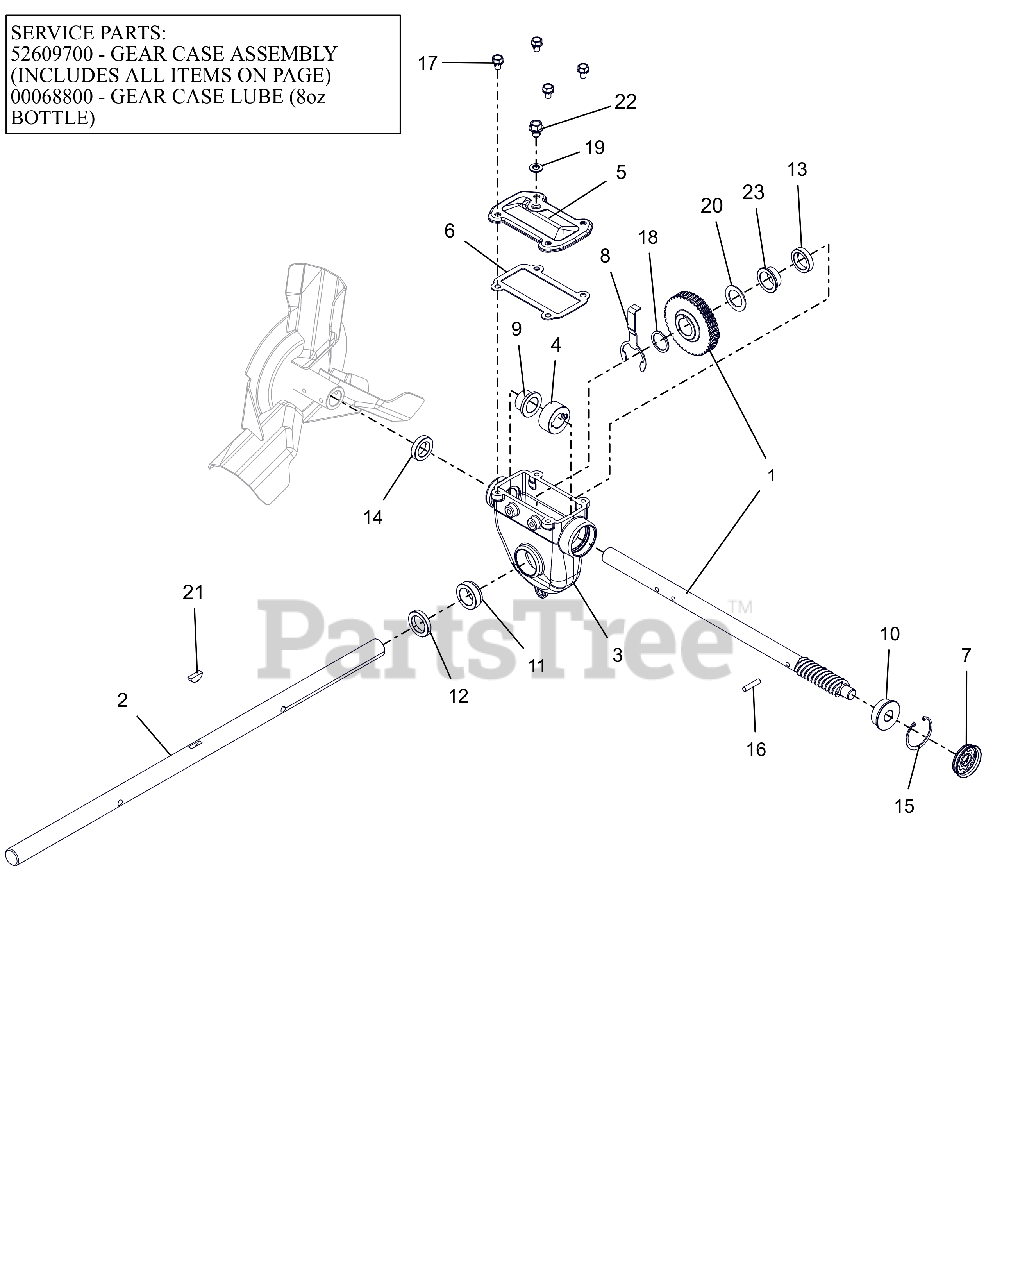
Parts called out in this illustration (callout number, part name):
1	ASSY, WORM SHAFT & GEAR
2	SHAFT, RAKE-28"
3	GEARCASE, LARGE MACHINED
3	GEAR CASE, 28" IRON PRO TOP-LD
3	ARIENS L3 LUBE, 8 OZ BOTTLE
4	THRUST COLLAR, .875"ID SLIPFIT
5	COVER, TOP - LARGE IRON
6	GASKET, TOP - LARGE GEARCASE
7	COVER, GEAR CASE 1.75"
8	BUSHING RETAINER, LARGE
9	BSHG-FLG .879X1.128X.75X1.45
10	BSHG-FLG .628X1.503X.58X1.725
11	BSHG-FLG LARGE, RIGHT
12	SEAL-OIL .999X1.500X.250 TBC29
13	SEAL-OIL .999X1.375X.312 TBC29
14	SEAL-OIL .873X1.375X.312 TBC29
15	RG-RTNG-INT 1.750X.062
16	PIN-STR .250X1.12 6150
17	BLT, SEMS .31-18X.50 G5 ZCC
18	WSHR, FLT 1.010X1.250X.068 ZCC
19	WSHR-BND-SEAL .38X.75X.11 GALV
20	WSHR, FLT 1.010X1.505X.062 ZCC
21	KEY-WDRF .25X.875 HRD #A
22	SCR,TAP .38-15X.50 HWH ROLOK
23	BSHG-FLG 1.006X1.128X.555X1.45
